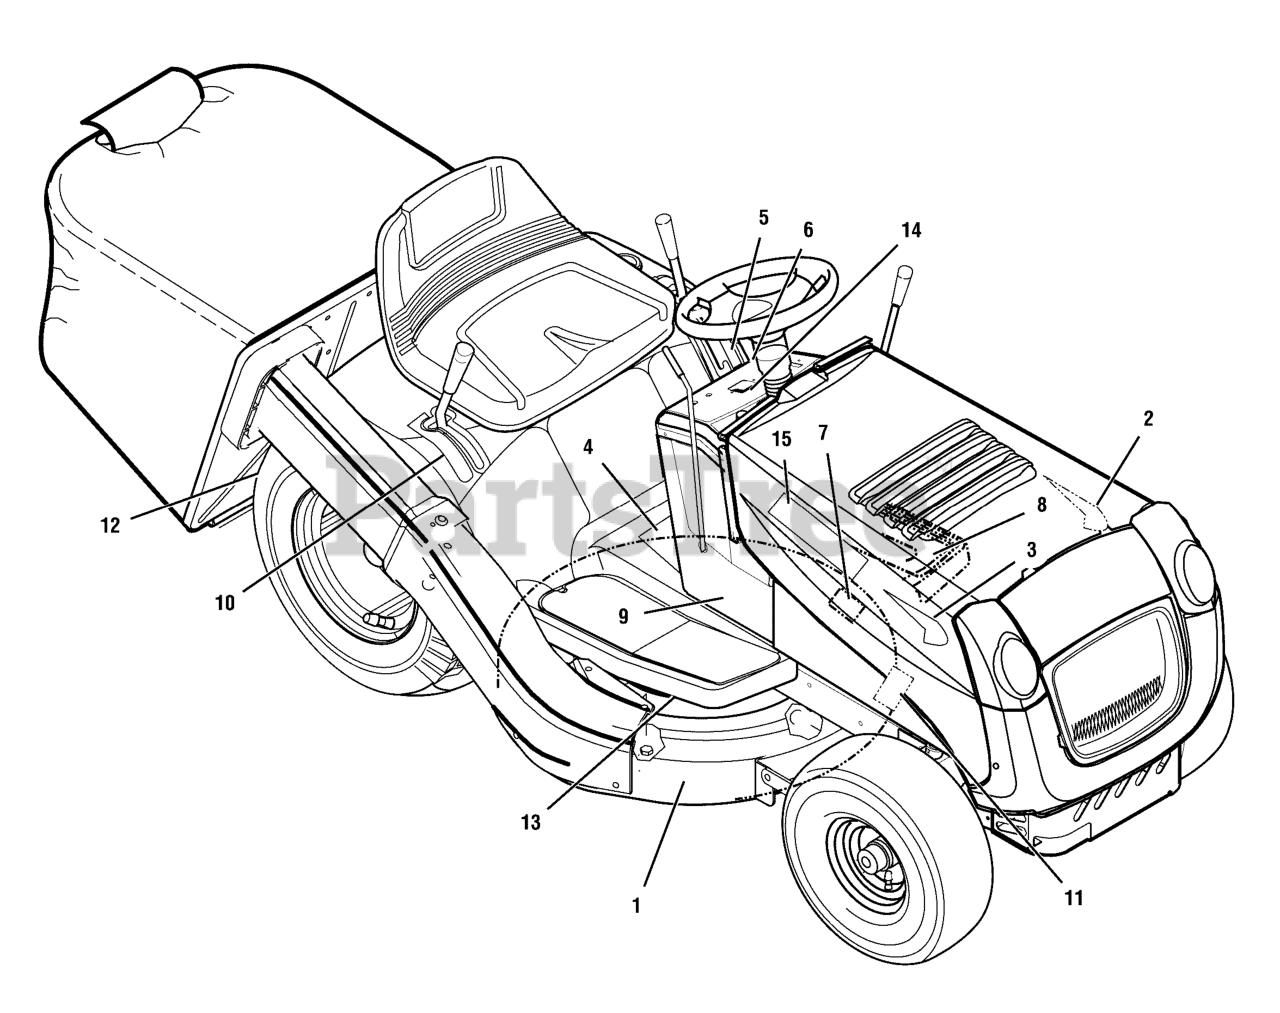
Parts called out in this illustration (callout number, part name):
1	DECAL, CUT FINGER SYMBOLS
2	DECAL, 125/76 LH
3	DECAL, 125/76 RH
4	DECAL, WARNING EXPORT
5	DECAL, 7 POS CUT HGT SM SD
6	DECAL, DECK LEVEL
7	DECAL, NO STEP EXPORT
8	DECAL, BRAKE/CLUTCH EXP
9	DECAL, B&S LOGO IC
10	DECAL, 5 SPEED
11	DECAL, HEAT SHIELD WARNING
12	DECAL, DRAWBAR WARNING PICT
13	DECAL, WARNING-PINCH POINT
14	DECAL, DASH/SYMBOLS W1
15	DECAL, SENTINEL R & L
